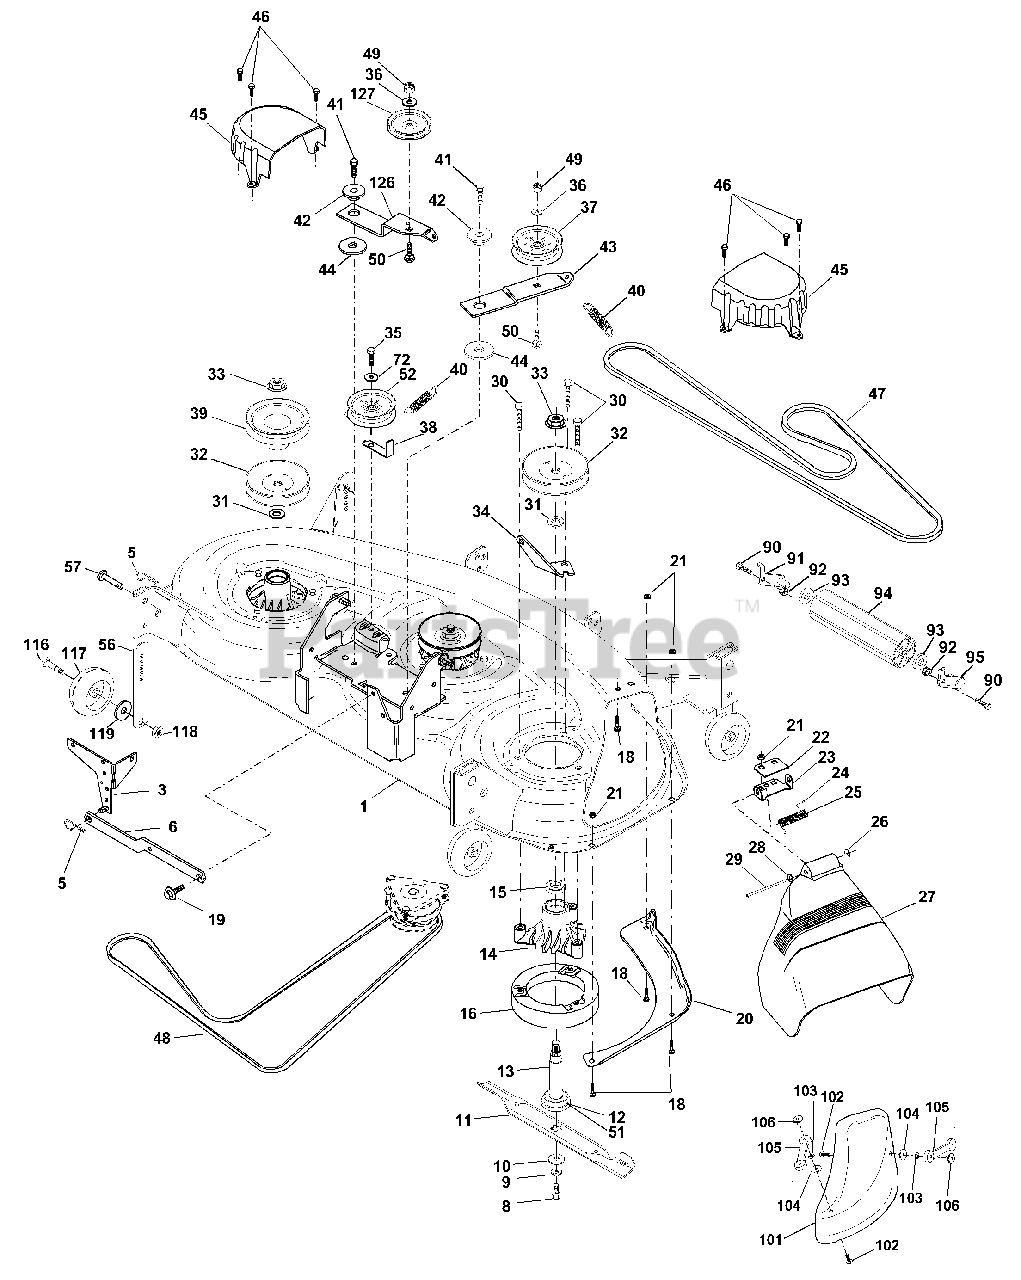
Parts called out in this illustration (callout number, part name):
1	Deck Asm., Mower 46"
3	Bracket Asm., Sway Bar
5	Retainer Spring
6	Arm, Suspension, Rear (Sway Bar)
8	Bolt, Patched 3/8-24 x 1-1/4 Gr. 8
9	Washer, Lock Hvy., Unplated 3/8
10	Washer, Hard Blade, Mower Vented
11	Blade, 46" Hi Perf
11	Blade, 46" Mulching
12	Bearing, Ball, Mandrel #6204
13	Shaft Asm. w/Lower Bearing
14	Housing, Mandrel
15	Bearing, Ball, Mandrel
16	Stripper, Mower Round
18	Bolt, Carriage 5/16-18 x 5/8
19	Bolt, Hex Head, Shoulder 5/16-18
20	Baffle, Vortex Mower 46"
21	Nut, Crownlock 5/16-18 UNC
22	Stiffener, Bracket
23	Bracket, Deflector
24	Cap, Sleeve
25	Spring, Torsion, Deflector
26	Nut, Push
27	Shield, Deflector Mower
28	Washer 11/32 x 5/8 x 16 Ga.
29	Rod, Hinge
30	Screw, Wsh Head, Thdroll
31	Washer, Spacer Mower Vented
32	Pulley, Mandrel
33	Nut, Flg. Top Lock Cntr. 9/16
34	Anchor, Spring Deck 46"
35	Screw, Thdroll 3/8-16 x 1-3/4 Tytt
36	Washer 13/32 x 13/16 x 16 Ga.
37	Pulley, Idler, Flat
38	Keeper, Belt, Idler
39	Pulley, Idler, Driven
40	Spring, Secondary 44/46/50 Vent
41	Screw 3/8-16 x 1-1/4
42	Spacer, Retainer
43	Arm, Idler Secondary
44	Washer,Hardened
45	Cover, Mandrel Deck
46	Screw, Thdroll. 1/4-20 x 5/8
47	V-Belt, Mower, Secondary
48	V-Belt, Mower, Primary
49	Nut, Crownlock 3/8-16 UNC
50	Bolt, Carriage 3/8-16 x 1-1/2 Gr. 5
51	Washer, Felt
52	Pulley Idler 46 Pri. Drive
56	Bar Adjusting Gage wheel
57	Pin Head Rivet
72	Washer 13/32 x 1 x 16 Ga.
90	Bolt, Fin, Hex 3/8-16 UNC x 1
91	Bracket, Asm Noseroller, LH
92	Nut, Lock, Hex w/Ins 3/8-16UNC
93	Washer 17/32 x 7/8 x 16 Ga.
94	Roller, Nose 38 & 42
95	Bracket, asm Noseroller RH
101	Cover Mulcher 46" Black
102	Screw Phillips Truss Head
103	Washer Lock #10
104	Washer #10
105	Latch Asm mulch/Bagger
106	Nut Weld
116	Bolt, Shoulder
117	Gauge Wheel
118	Nut, Centerlock 3/8-16 UNC
119	Washer 3/8 x 7/8 x 14 Ga.
126	Arm, Idler, Primary Deck 46"
127	Pulley, Idler, V-Groove Dim. 4.25
